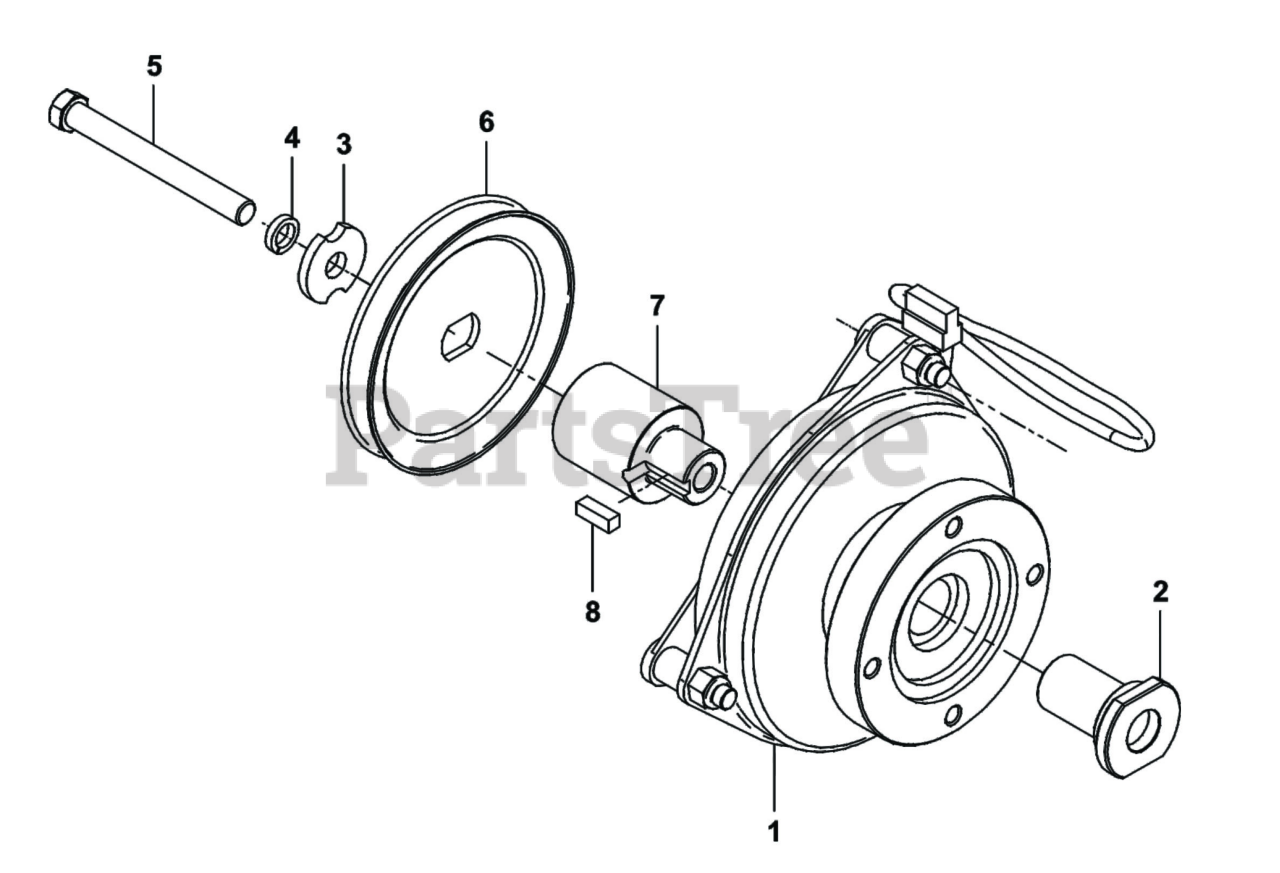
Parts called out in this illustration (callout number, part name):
1	ELECTRIC CLUTCH (110 FT-LBS)
2	CLUTCH SHAFT
3	WASHER-7/16 x 1-3/
4	LOCK WASHER 7/16"
5	SCREW 7/16"-20 X 4"
7	ENGINE PULLEY BUSHING #27
8	KEY, 1/4" X 3/4" LG
